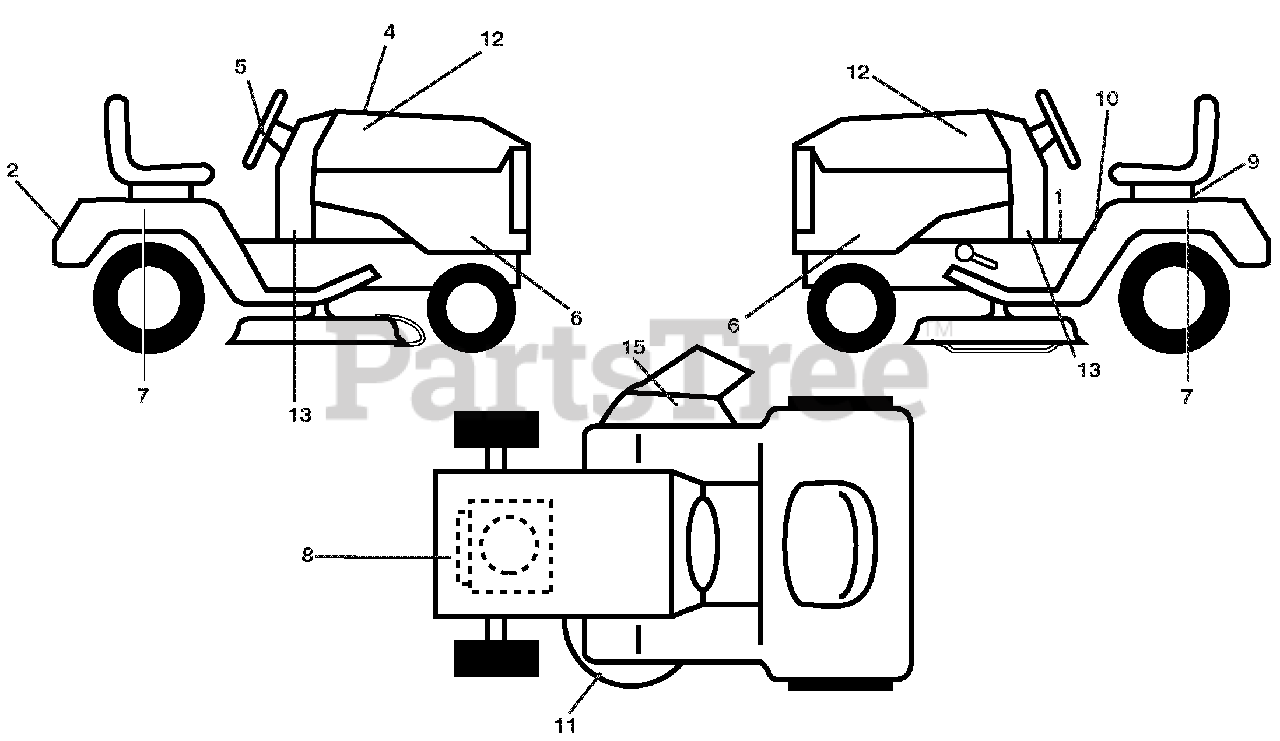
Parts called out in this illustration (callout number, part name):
1	DECAL.WARNING.START
2	DECAL.FENDER.REAR.ARIENS
4	DECAL.REPLACEMENT
5	DECAL.WHEEL.STEER.ARIENS
6	DECAL.SDPNL.PWRDBY B&S.ARIENS
7	DECAL.FENDER.SIDE.HYDRO
8	DECAL.ENGINE.HP
9	DECAL.BAT.DAN/POI P/L SYM.WPN
10	DECAL.FENDER
11	DECAL.V-BELT.SCH.
12	DECAL.HOOD.LH/RH.
13	DECAL, DASH.LOWER
15	DECAL DECK/DEFLECT. WARNING
